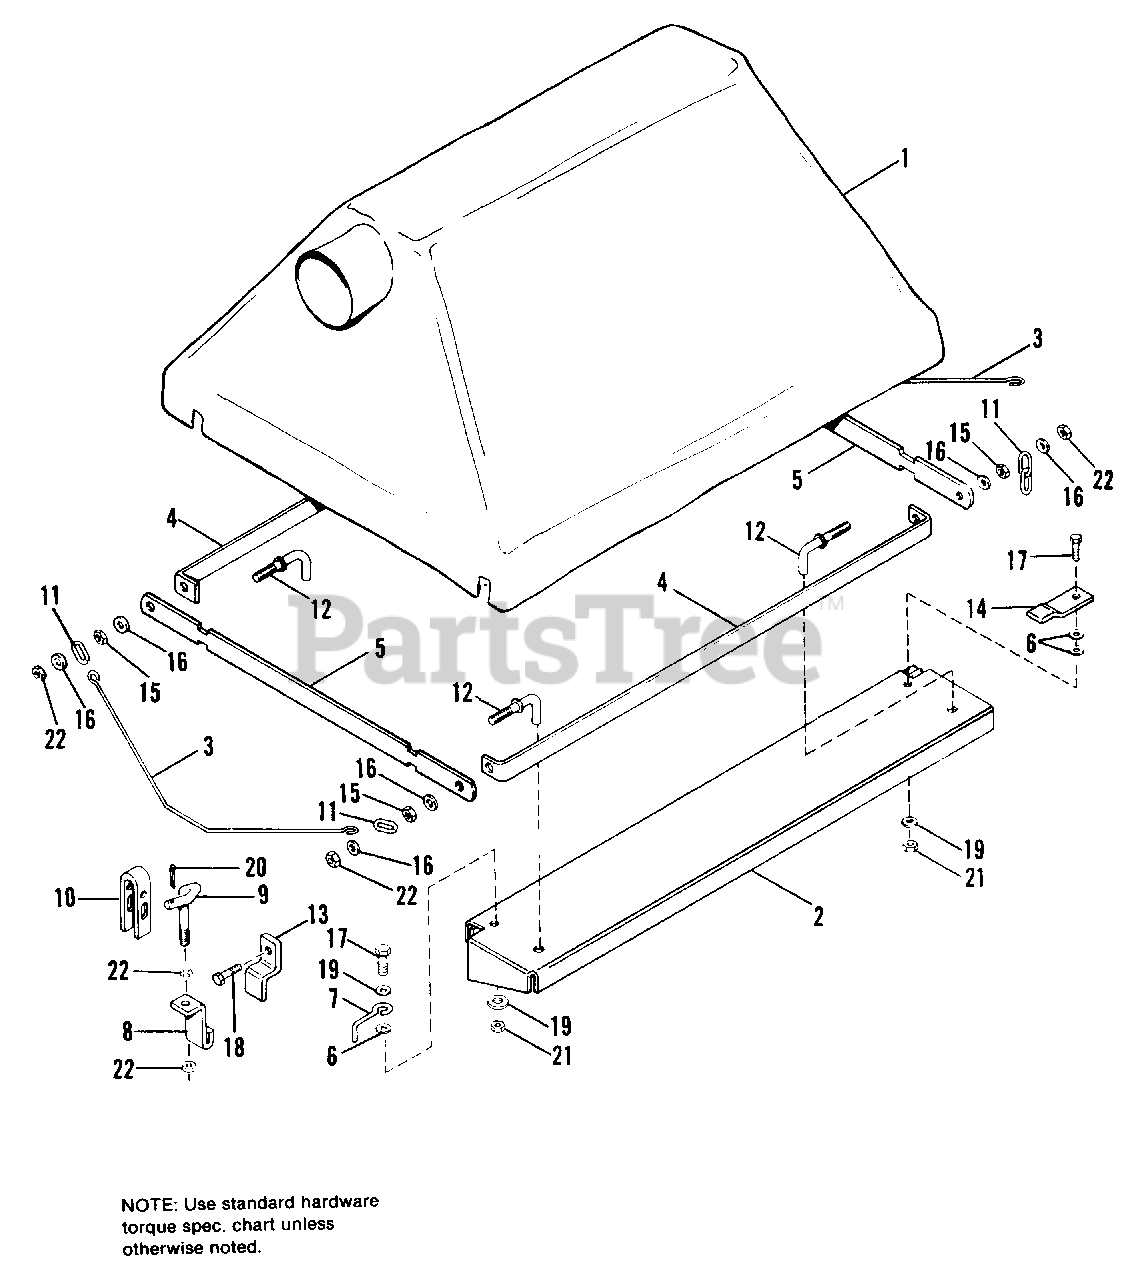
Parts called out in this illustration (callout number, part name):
1	COVER, Cart
2	PANEL, Side
4	BAR, Reinforcement, Side
5	BAR, Reinforcement, End
6	WASHER, Special
7	STOP, Belt
9	LATCH, Rod
11	LINK, Repair
15	NUT, Hex, 3/8-16
16	WASHER, Plain, 3/8
17	CAPSCREW, Hex Hd., 5/16-18 x 3/4
18	CAPSCREW, Hex Hd., 3/8-16 x 1-1/4
19	WASHER, Plain, 5/16
20	COTTER PIN, 1/8 x 1
21	LOCKNUT, Hex, 5/16-18 x 17/64
22	LOCKNUT, Hex, Full, 3/8-16
